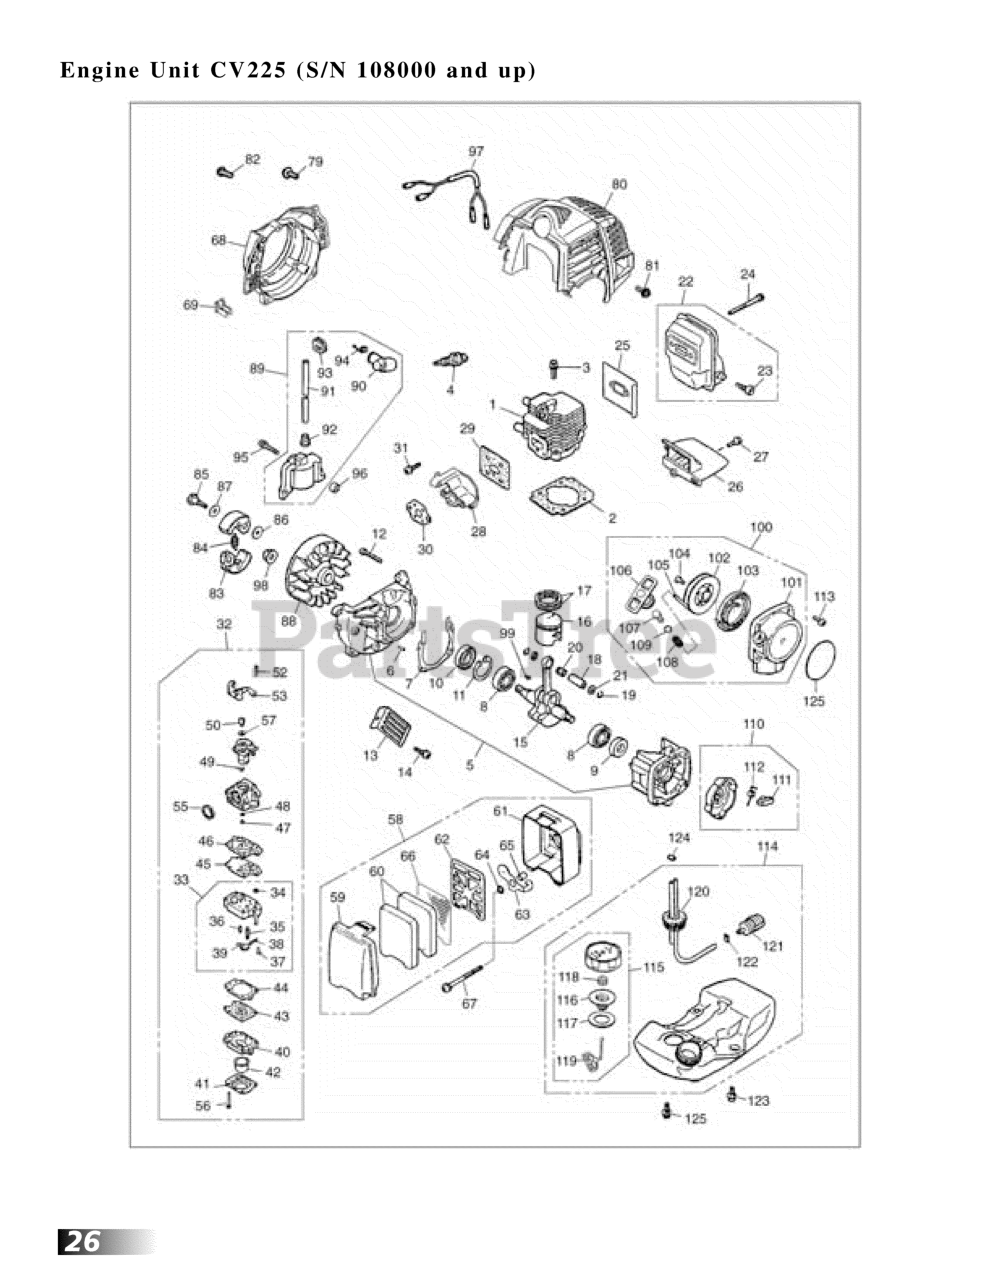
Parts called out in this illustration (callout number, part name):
1	CYLINDER
2	GASKET, BASE (RPLS -12212)
3	BOLT, M5 X 22
5	CRANKCASE
6	PIN
7	GASKET (RPLS -21140)
8	BEARING
9	SEAL, OIL (RPLS 1100-21210)
10	SEAL, OIL (RPLS 1140-21220)
11	RING, SNAP, M28 x 1.2
12	BOLT, M5 X 30
14	SCREW,M5 X 14 (RPLS 1400-15510
15	CRANKSHAFT (RPLS 1850-42000)
16	PISTON (REPLACES 1140-41110)
17	RING, PISTON (RPLS 1850-41210)
18	PIN, PISTON 5x8x26
19	RING, SNAP (RPLS 1101-41320)
20	BEARING (RPLS 1140-41330)
21	WASHER
22	MUFFER ASSEMBLY
23	ARRESTER (RPLS 5850-15140)
24	BOLT, M5 x 50
25	GASKET
26	PLATE, MUFFLER (RPLS -15220)
27	SCREW, M4 X 16
28	INSULATOR
29	GASKET (RPLS -13120)
30	GASKET (REPLACES -13130)
31	SCREW, M5X20 (RPLS.1400-75510)
32	CARBURETOR ASSY.
33	BODY, PUMP
35	VALVE, INLET
36	SPRING, METERING LEVER
37	SCREW, METERING LEVER PIN
38	PIN, METERING LEVER
39	LEVER
40	BODY, PURGE
41	COVER, PUMP
42	PUMP, PRIMING
43	DIAPHRAGM (USE 4810-81260)
44	GASKET, DIAPHRAGM
45	DIAPHRAGM
46	GASKET, PUMP
47	JET
48	RING, O
49	RING
50	SWIVEL
52	SCREW
55	RING, PACKING
56	SCREW
57	WASHER
58	CLEANER ASSY (RPLS -82000)
59	COVER
60	FILTER
61	HOUSING
62	PLATE
64	WASHER
65	SLEEVE (REPLACES 1750-82060)
66	SCREEN
67	SCREW, M5 x 60
68	COVER, FAN
69	CLAMP
79	SCREW, M5X20 (RPLS.1400-75510)
80	COVER, ENGINE (USE -32111)
81	SCREW (RPLS-32161)
82	SCREW, M5 X 10
83	SHOE
84	SPRING
85	BOLT
86	WASHER, FLAT (USE 182303)
88	ROTOR
89	COIL-A (REPLACES -71200)
90	CAP
91	CORD
92	CAP
93	GROMMET
94	SPRING
95	BOLT
96	SPACER
97	CORD COMP
99	KEY
100	RECOIL ASSEMBLY
101	CASE
102	REEL
103	SPRING, SPIRAL
104	SCREW (RPLS -75150)
105	ROPE
106	KNOB
107	COLLAR
108	SPRING
109	WASHER
110	PULLEY ASSY (RPLS -75210)
111	RATCHET (RPLS 1850-75220)
112	SPRING, RETURN
113	SCREW (RPLS-32161)
114	TANK ASSY (RPLS -85000)
115	CAP ASSY (RPLS. 5601-85201)
116	HOLDER - A (RPLS 5601-85230)
117	PACKING
118	FILTER
119	STOPPER
120	PIPE COMPLETE
121	FILTER (RPLS 1850-85300)
122	CLIP (REPLACES 2841-31280)
123	SCREW W/ WASHER
124	CLIP
125	SCREW
126	LABEL
